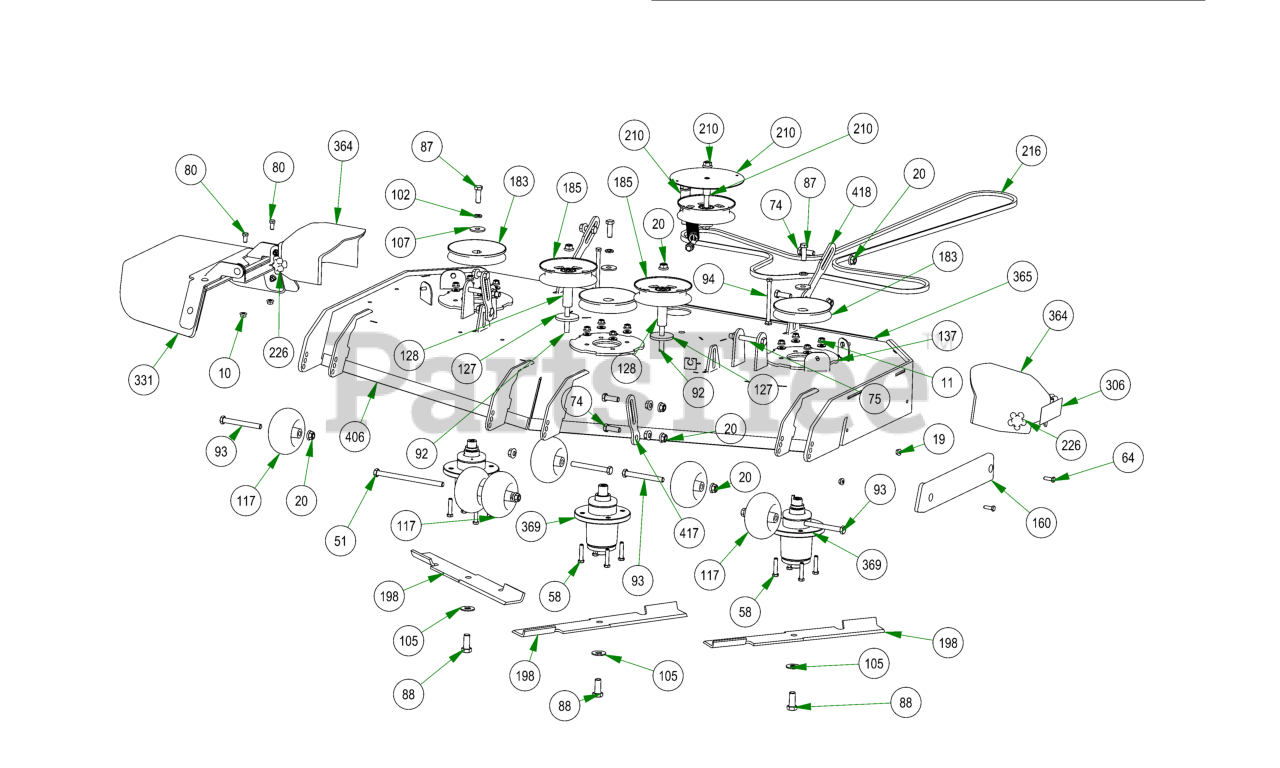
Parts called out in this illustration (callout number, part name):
10	3/8-16 HEX SERRATED FLANGE NUT HARD/ZINC
11	3/8-16 NYLON INSERT FLANGE LOCKNUT (GR.F) ZINC
12	1/2-13 HEX SERRATED FLANGE NUT HARD/ZINC
13	5/8-11 NYLON INSERT JAM LOCKNUT ZINC
16	1/2-13 HEX NUT ZINC
19	5/16-18 NYLON INSERT FLANGE LOCKNUT ZINC
20	1/2-13 NYLON INSERT FLANGE LOCKNUT ZINC
51	1/2-13 X 8 HEX CAP SCREW GR 5 ZINC
58	3/8-16 X 1-3/4 HEX C/S (GR.5) ZC
62	All Thread
64	5/16-18 X 1 HEX CAP SCREW (GR.5) ZINC
74	1/2-13 X 1-1/2 HEX CAP SCREW (GR.5) ZINC
75	1/2-13 X 4 HEX CAP SCREW (GR.8) ZINC YELLOW
80	3/8-16 X 3/4 HEX CAP SCREW (GR.5) ZINC
82	5/8-11 X 4 HEX CAP SCREW (GR.8) ZINC YELLOW
87	1/2-20 X 1-1/2 HEX CAP SCREW (GR.5) ZINC
88	5/8-18 X 1-1/2 HEX CAP SCREW (GR.8) ZINC YELLOW
92	1/2-13 X 4-1/4 HEX CAP SCREW (GR.5) ZINC
93	1/2-13 X 4-1/2 HEX CAP SCREW (GR.5) ZINC
94	3/8-16 X 5-1/2 HEX CAP SCREW (GR.5) ZINC
98	5/16-18 X 1 CARRIAGE BOLT (GR.8) ZINC
102	1/2 SPLIT LOCKWASHER (GR.8) ZINC/YELLOW
105	5/8 USS FLAT WASHER (1-3/4" OD) GR.8 ZINC YELLOW
106	.635 ID X 1.120 OD X .140 THICK FLAT WASHER NYLON
107	1/2 BELLEVILLE WASHER (1-5/8 OD X .140 THK) ZINC
110	.360 ID X .983 OD X .120 THICK FLAT WASHER NYLON BLACK
113	5/16 USS FLAT WASHER (7/8 OD) ZINC
117	2019 Deck Wheel
127	MZ Deck Idler Spacer
128	2019 Revolt Stationary Idle Spacer
137	Deck Spindle Support Plate
160	REVISED TRIM BUMPER_20180226
163	5/16-24 X 1/4 SOCKET SET SCREW (CUP PT) PLAIN
183	6 1/4" Drive Pulley
185	5-3/4 Idler Pulley
190	2019 Outlaw Gen2 Deck Spring
198	61 inch Fusion Blade
210	2020 61 Revolt Deck Idler Assembly
223	1/4 X 1 SQ MACHINERY KEY 1018 STL PLN
226	5/16" Knob
229	Turnbuckle
246	1.02 ID X 1.38 OD X .250 THK SPACER ZINC
304	2018 61" Deck Decal
306	Danger Decal-Spindle/Discharge
318	2019 Revolt Deck Belt Route Decal
326	Deck Impact Patent Decal 9591803
331	2019 Outlaw Gen2 Chute Assembly
364	2023 Revolt pulley cover
365	R Series Rubber For Deck
366	61 Bolt in Baffle Deck v2 Stripping Plate
369	OUTLAW SPINDLE ASSEMBLY
406	2023 61'' DECK
417	2023 revolt 61 front hanger V2
418	2023 Stand-On Rear Deck HangerV2
